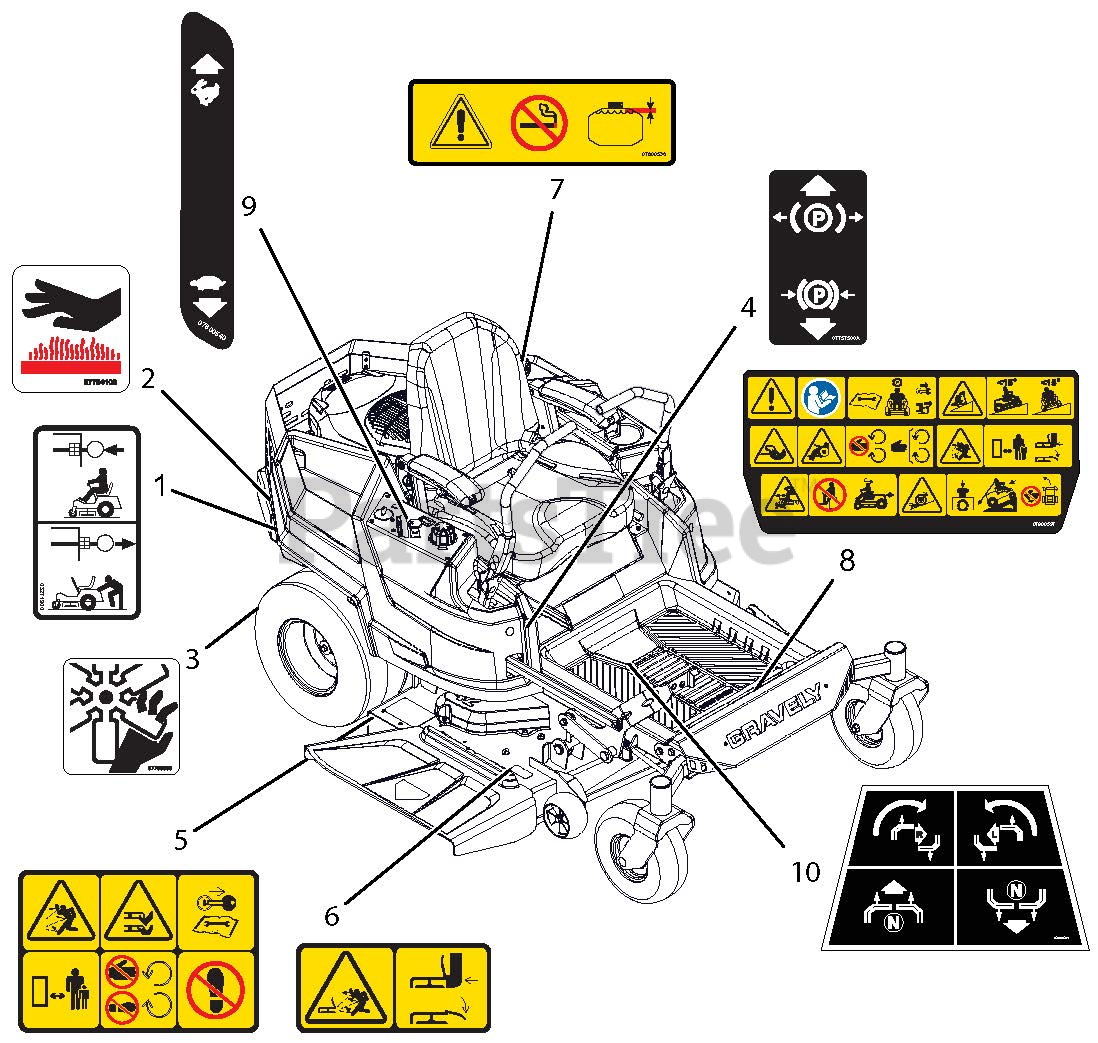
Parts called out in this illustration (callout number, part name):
1	DECAL, TRANSMISSION DISCONNECT
2	DECAL HOT SURFACE
3	DECAL, DANGER - FAN
4	DECAL, PARKING BRAKE LEVER
5	DECAL, SAFETY - MOWER DECK
6	DECAL, SAFETY - DECK GUARDING
7	DECAL, FUEL WARNING
8	DECAL, MAIN SAFETY-IKON ZTX
9	DECAL, DASH
10	DECAL, STEERING
